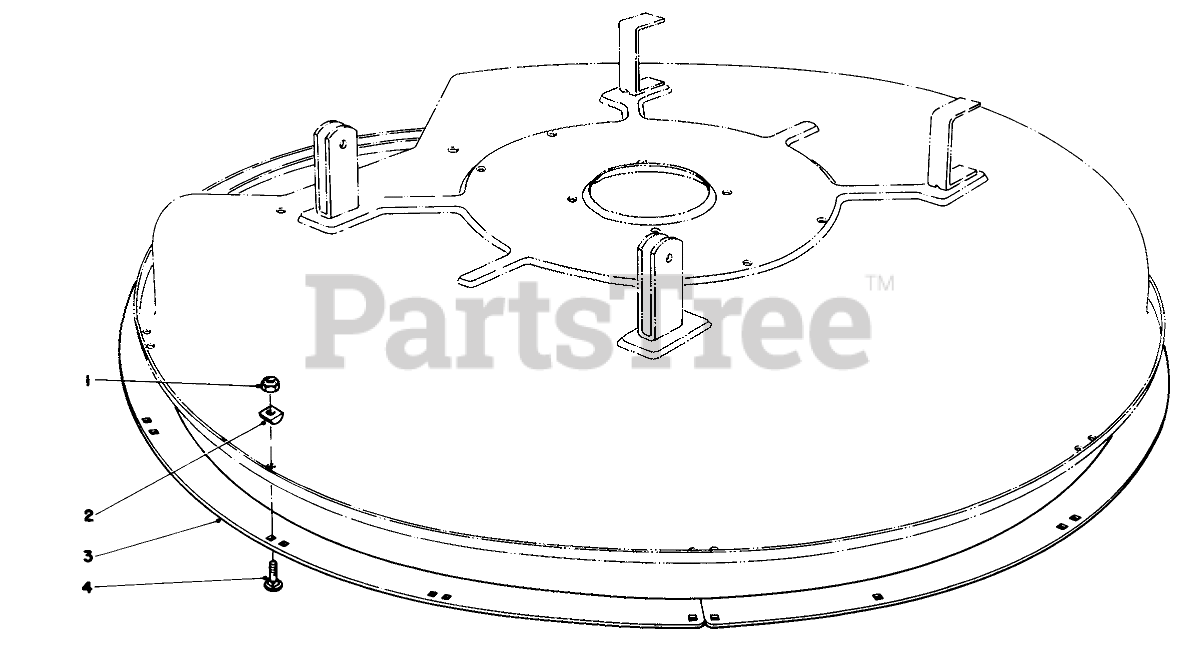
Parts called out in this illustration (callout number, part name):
1	NUT-LOCK, NI
2	DECK RING SPACER
3	DECK RING B
4	BOLT-CARR
